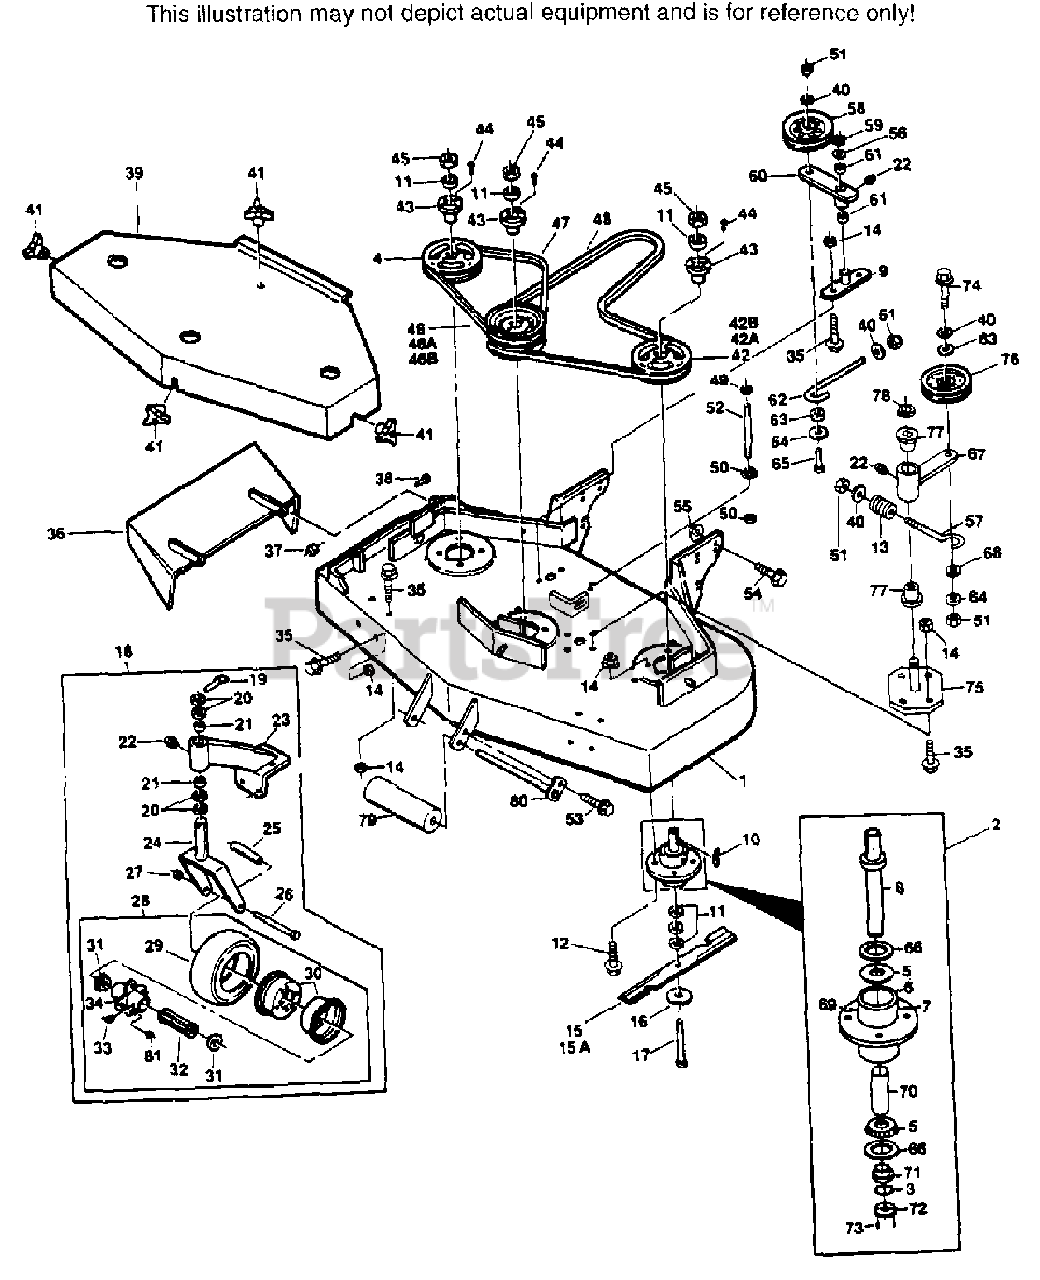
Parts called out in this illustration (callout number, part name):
2	SPINDLE ASSEMBLY
3	RETAINING RING, 1" EXTERNAL INVERTED
4	PULLEY
5	TAPERED BEARING
6	SPINDLE HOUSING
7	GREASE FITTING STR. 5/16 SERRATED
8	SPINDLE SHAFT, TAPERED BEARING
9	IDLER PIVOT
10	KEY, 1/4 X 1/4 X 2"
11	SPACER, CUTTER BLADE - SMALL
12	CAPSCREW 5/16-18 X 1-1/4"
13	SPRING, CUTTER DECK
14	SERRATED FLANGE NUT, 5/16-18
16	FLATWASHER, 5/8" W
17	HEX HEAD BOLT, 5/8-11 X 9-1/2"
18	CASTER ASSEMBLY,(INCL. 19-28)
19	QUICK PIN
20	SPACER, CASTER YOKE, 1/2" THICK
21	BRONZE BEARING
22	GREASE FITTING
23	SUPPORT ASSEMBLY,(INCL. 21-23)
24	CASTER YOKE
25	SLEEVE, CASTER WHEEL BEARING
26	HEX HD BOLT, 1/2-13 X 5-1/2"
27	ELASTIC STOP NUT, 1/2-13
28	WHEEL ASSY.(INCL. 29-34,81)
29	TIRE ONLY, CASTER WHEEL
30	RIM PAIR, CASTER WHEEL
31	BEARING RETAINER, CASTER WHEEL
32	ROLLER BEARING, CASTER WHEEL
33	GREASE FITTING 45 DEG., 1/4-28
34	HUB ASSEMBLY,(INCL. BOLTS)
35	CAPSCREW, 5/16-18 X 3/4"
37	HEX NUT, 5/16-18 ELASTIC STOP
40	FLAT WASHER, 3/8" SPECIAL
41	WING NUT, 3/8-16
43	TAPERED HUB
49	HEX NUT, 3/8-16, CENTERLOCK
50	NUT, 3/8-16, SERRATED FLANGE
51	ELASTIC STOP NUT, 3/8-16
52	SUPPORT, BELT COVER
53	CAPSCREW, 5/16-18 X 1/2" SERRATED FLANGE HEX
54	CAPSCREW, 7/16-14 X 1" SERRATED FLANGE HEX
55	NUT, 7/16-14 SERRATED FLANGE
56	FLAT WASHER 3/4" SPECIAL
56A	FLAT WASHER 3/4" SPECIAL
57	J-HOOK
58	IDLER PULLEY, "V" GROOVE
59	RETAINING RING, 3/4" EXT. "E"
60	IDLER ARM ASSY.(INCL. 22 & 61)
61	BRONZE BEARING
62	J-ROD, IDLER PULLEY
63	SPACER, J-ROD
64	WASHER, 3/8 X 1-1/2 X 16 GA.
66	SEAL
67	IDLER ARM ASSY(INCLUDES 22&77)
68	SPACER, J-ROD
69	RELIEF FITTING, CUTTER SPINDLE
70	SLEEVE, CUTTER SPINDLE
71	SPINDLE BUSHING
72	SPACER, LARGE
75	IDLER PIVOT
76	IDLER PULLEY, BELT CLUTCH
77	BRONZE BEARING
78	RETAINING RING
79	GUIDE ROLLER
80	ROLLER SHAFT
NS	INNER TUBE ONLY, CASTER WHEEL
